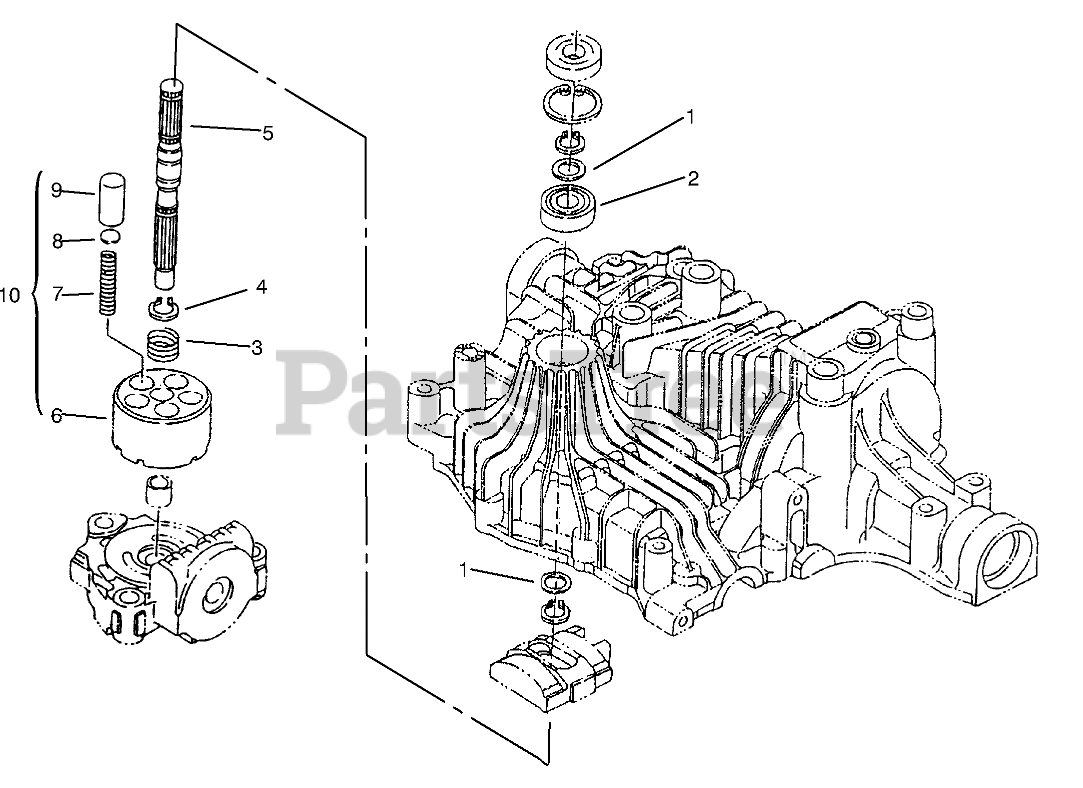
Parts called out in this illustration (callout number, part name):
1	WASHER
2	BEARING-BALL
3	SPRING
4	RING-SNAP
5	SHAFT - PUMP
6	Block-Cylinder
8	Washer
10	ASM - CYCLINDER INC 6-9
